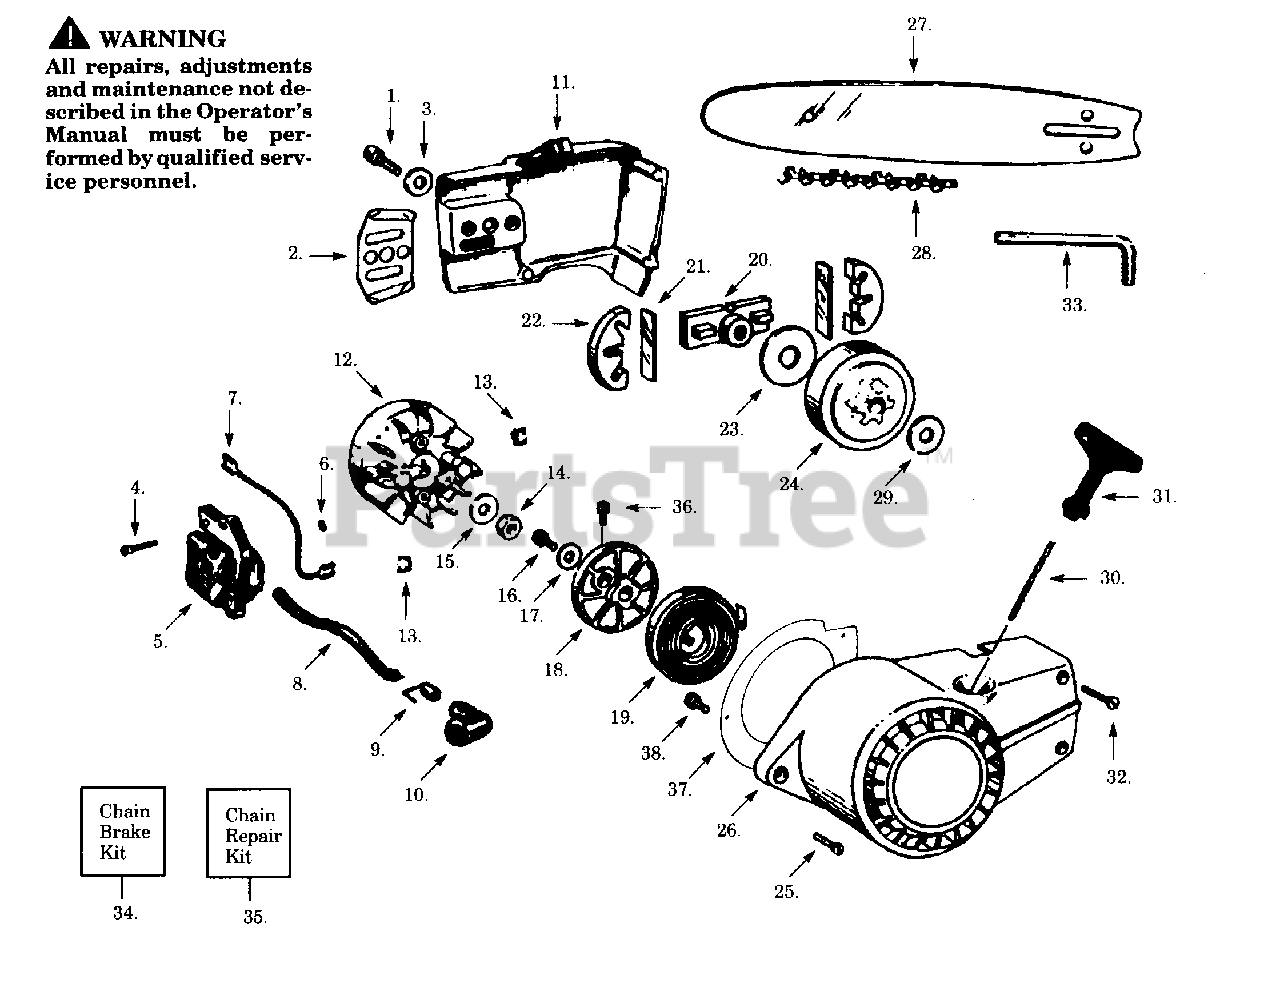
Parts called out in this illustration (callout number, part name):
2	Guide Plate
4	Screw
5	Ignition Module
6	Flywheel Key
7	Lead Stop Switch
8	High Tension Lead (Bulk No. 8141)
9	Connector Spring Plug
10	Spark Plug Boot
11	Bar Clamp
12	Flywheel Ass'y.
13	Starter Dog Spring
18	Starter Pulley
19	Starter Spring
20	Clutch Spider
21	Clutch Springs
22	Clutch Shoes
23	Clutch Plate
24	Drum & Sprocket Ass'y.
26	Fan Housing
27	14" Sprocket Nose
27	16" Sprocket Nose
28	14" (P101S-52)
28	16" (P101S-56)
29	Clutch Washer
30	Rope Kit
31	Starter Handle
33	Bar Wrench
34	Chain Brake Kit
35	Chain Repair Kit
37	Air Inlet Baffle
